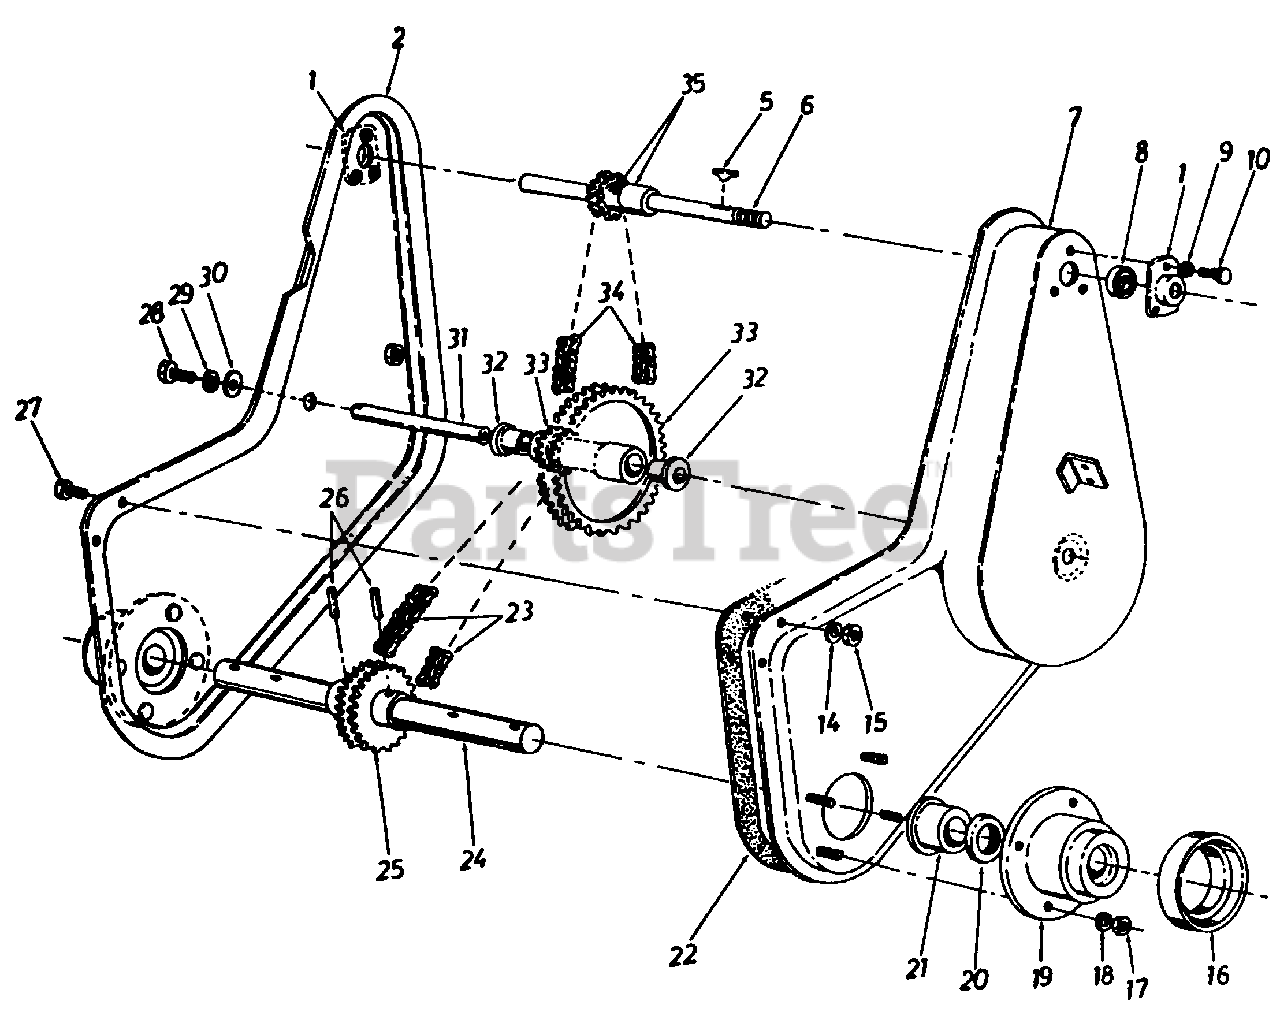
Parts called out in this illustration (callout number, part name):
1	Bearing Housing 1.375" Dia.
6	Input Shaft Assembly
9	L-Wash. 1/4" I.D.
10	Hex Bolt 1/4-20 x .62" Lg.
14	L-Wash. 1/4" I.D.
15	Hex Cent. L-Nut 1/4-20 Thd.
16	Dust Cap Cover
17	Hex Cent. L-Nut 5/16-18 Thd.
18	L-Wash. 5/16" I.D.
19	Cast Bearing Housing
21	Flange Bearing 1.25" I.D. x 1.75" O.D.
23	Roller Chain #40-2 x 34.0"
24	Tine Shaft
25	Double Sprocket T24-2 Teeth 1/2" Pitch
26	Spiral Pin 3/8" Dia. x 2.00"
27	Hex Bolt 1/4-20 x .62" Lg.
28	Hex Bolt 5/16-18 x .75" Lg.
29	L-Wash. 5/16" I.D.
30	Fl-Wash. 5.16" I.D.
31	Sprocket Shaft
32	Flange Bearing .62" I.D. x .75" O.D.
33	Double Sprocket Assembly
34	Roller Chain #35-2 x 36.75" Lg.
35	Spacer 5/8" I.D. x 7/8" O.D.
